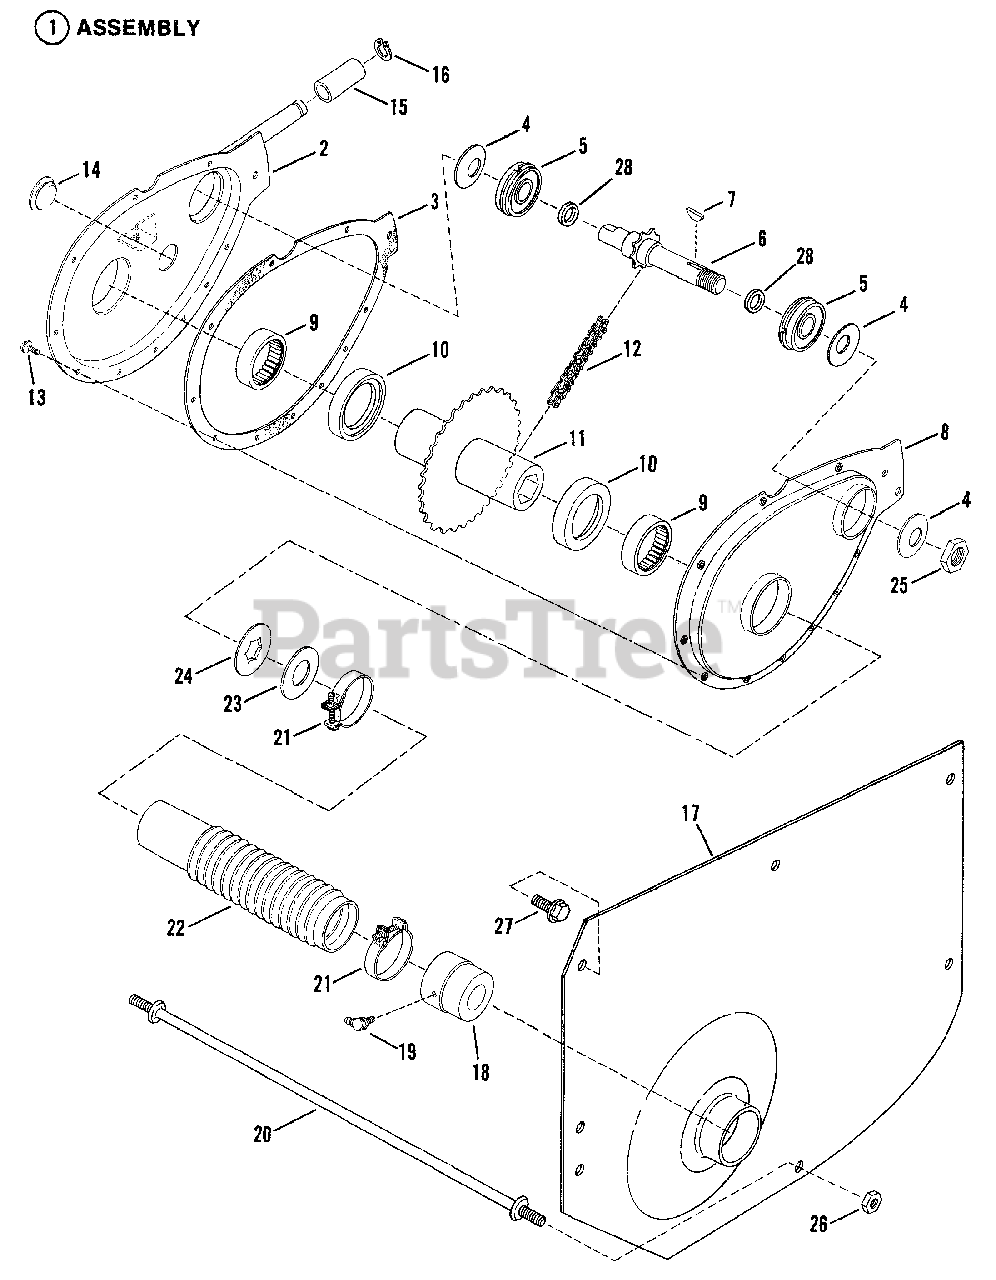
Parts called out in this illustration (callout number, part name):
1	ASSEMBLY, Chain Case
2	CASE, Sprocket
3	GASKET, Case-Cover
4	WASHER, Belleville
5	BEARING, Ball
6	SPROCKET & SHAFT
7	KEY, Woodruff
8	COVER, Chain Case
9	BEARING, Needle
10	WASHER, Nylon Thrust
11	HUB & SPROCKET
12	CHAIN
13	SCREW, #10-24 x 1/2" Hex Washer Self-Tap (Torx)
14	PLUG, Oil Fill & Check
15	ROLLER
16	RING, Retaining
17	FENDER, Left Hand
18	BEARING, Fender
19	FITTING, Lube
20	ROD, Cross Tie
21	CLAMP, Boot
22	BOOT, Oil Seal (Long)
23	WASHER, Thrust Nylon
24	WASHER, Thrust
25	NUT, 5/8-18 Hex Lock
26	NUT, 5/16-24 Hex
27	SCREW, 5/16-18x5/8" Self-Tapping
28	"O"-Ring
